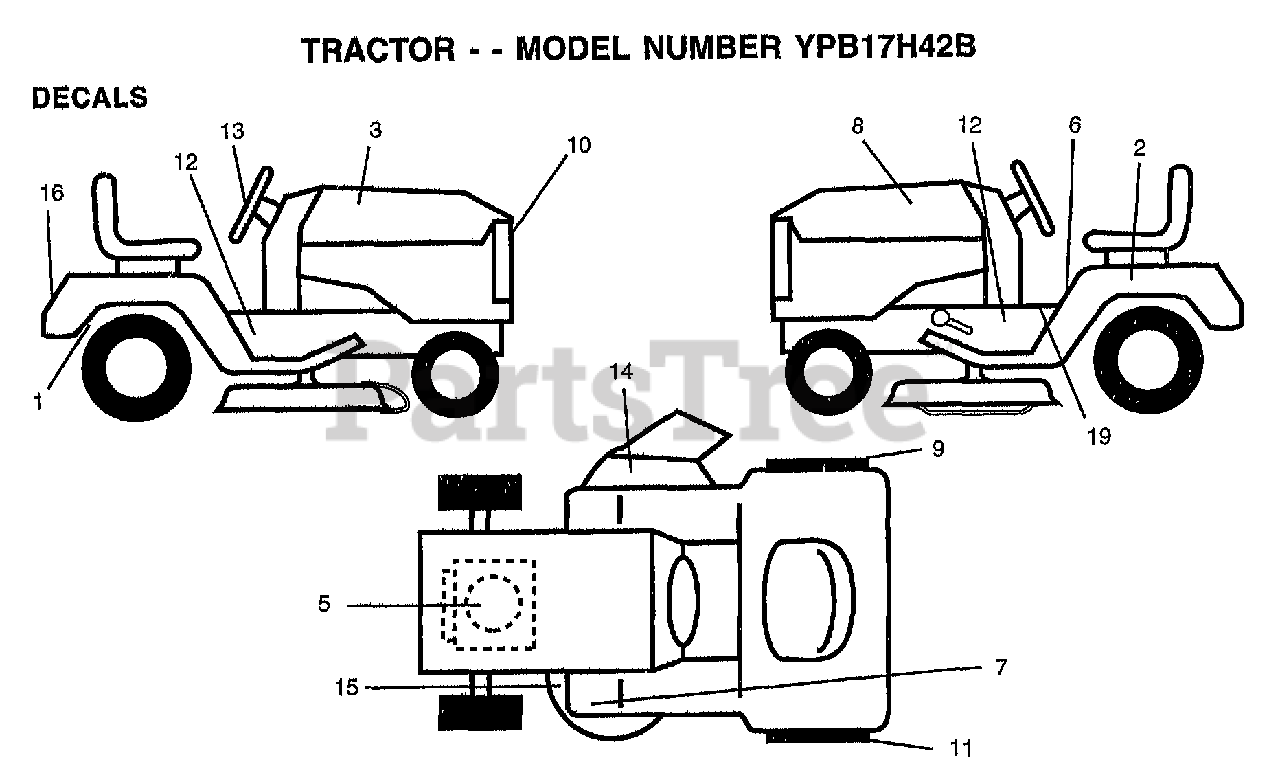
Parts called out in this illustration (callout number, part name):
1	DECAL BY PASS LT HYDRO
2	DECAL.BATRY.3-3908
3	DECAL.BATRY.3-3908
5	DECAL, HP ENGINE
6	DECAL.CAUT.ENG/FR
7	DECAL T
8	DECAL
9	DECAL FENDER RH
11	DECAL FENDER LH
12	DECAL CHASSIS
13	DECAL INS STRG WH
14	"DECAL, WARNING"
15	"DECAL-SCHEM,BELT"
16	DECAL FENDER
19	DECAL SADDLE OPER
